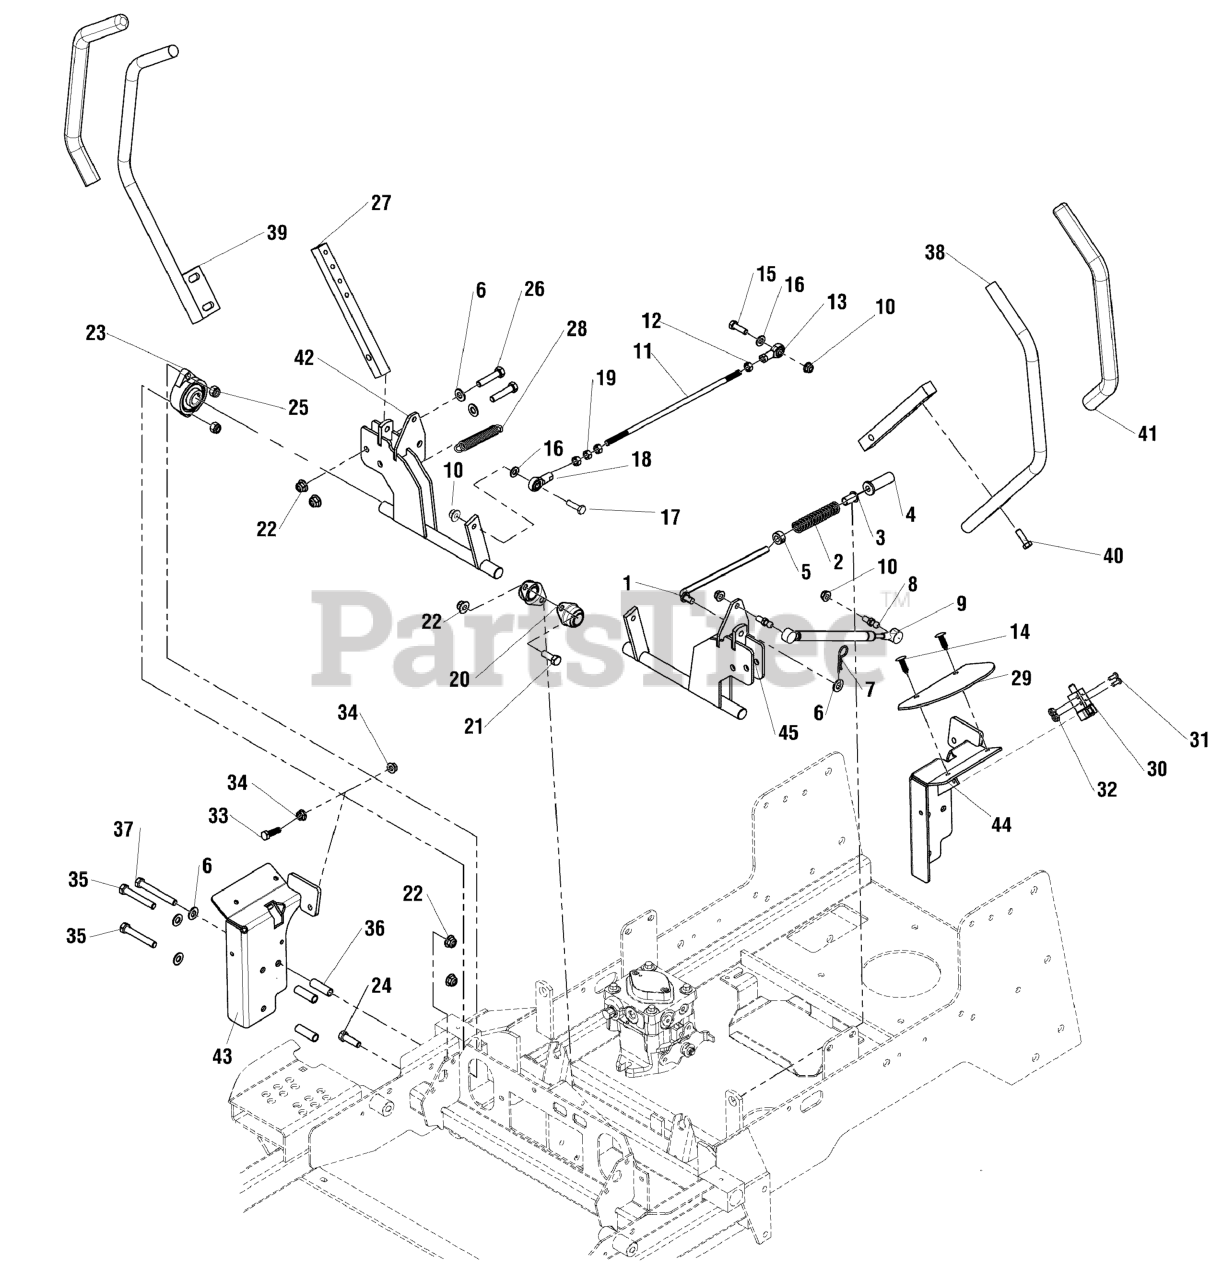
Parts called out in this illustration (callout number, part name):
1	ROD, NEUTRAL RETURN
2	SPRING, REVERSE RETURN
3	BUSHING, NYLON
4	FLANGED BUSHING, 3/8IDX.63ODX.8125FL
5	COLLAR, 3/8" SET
6	WASHER, 3/8 SAE
7	PIN, HAIR, .0915 X 1-7/8
8	BALL STUD, 5/16 X .50,# PC-477-2)
9	DAMPENER, CONTROL,#(P6709/P3610)
10	NUT, 5/16-18 HEX NYLOCK FLANGE
11	ROD, HYDRO LINKAGE
12	NUT, 5/16-24 HEX, LH
13	BALL JOINT 5/16-24 LH FEMALE BRONZE RACE
14	PUSH RIVET (TREE TYPE), BLACK
15	BOLT, 5/16-18 X 1" GD5 YZ
16	WASHER, 5/16" SAE
17	BOLT, 5/16-18 X 1-1/4" GD5 YZ
18	BALL JOINT 5/16-24 RH FEMALE BRONZE RACE
19	NUT, 5/16-24 HEX
20	BEARING, BRONZE FLANGE, 3/4
21	BOLT, 3/8-16 X 1" GD5 CZ
22	NUT, 3/8-16 HEX NYLOCK FLANGE
23	BEARING, FLANGE
24	BOLT, 3/8-16 X 1-1/4" GD5 CZ
25	NUT, 3/8-16 HEX NYLON LOCK
26	BOLT, 3/8-16 X 1-3/4" GD5 CZ
27	MOUNT, CONTROL ARM - BLK
28	SPRING, EXTENSION
29	GUARD, RUBBER MOTION CONTROLS
30	SWITCH, PLUNGER, N.O./N.C.
31	SCREW, #10-24 X 1/2" ROUND PHILLIPS
32	NUT, #10-24 HEX
33	BOLT, 5/16-18 X 1-1/8" GD5
34	NUT, 5/16-18 HEX SERRATED FLANGE (SMALL)
35	BOLT, 3/8-16 X 2-1/2" GD5 CZ
36	SPACER, .39 X .63 X 1.50
37	BOLT, 3/8-16 X 3" GD5 CZ
38	KIT, HANDLE BAR REPLACE, L/R
39	KIT, HANDLE BAR REPLACE, L/R
40	SCREW, 5/16-18x0.750, GR5, WHIZ-LOCK, ZC
41	GRIP, FOAM, 3/4" ID, 16" LONG
42	WELD, SHAFT MOTION CONTROL - RH - BLK
43	WELD, NEUTRAL LOCK, RH - BLK
44	WELD, NEUTRAL LOCK, LH - BLK
45	WELD, SHAFT MOTION CONTROL - LH - BLK
